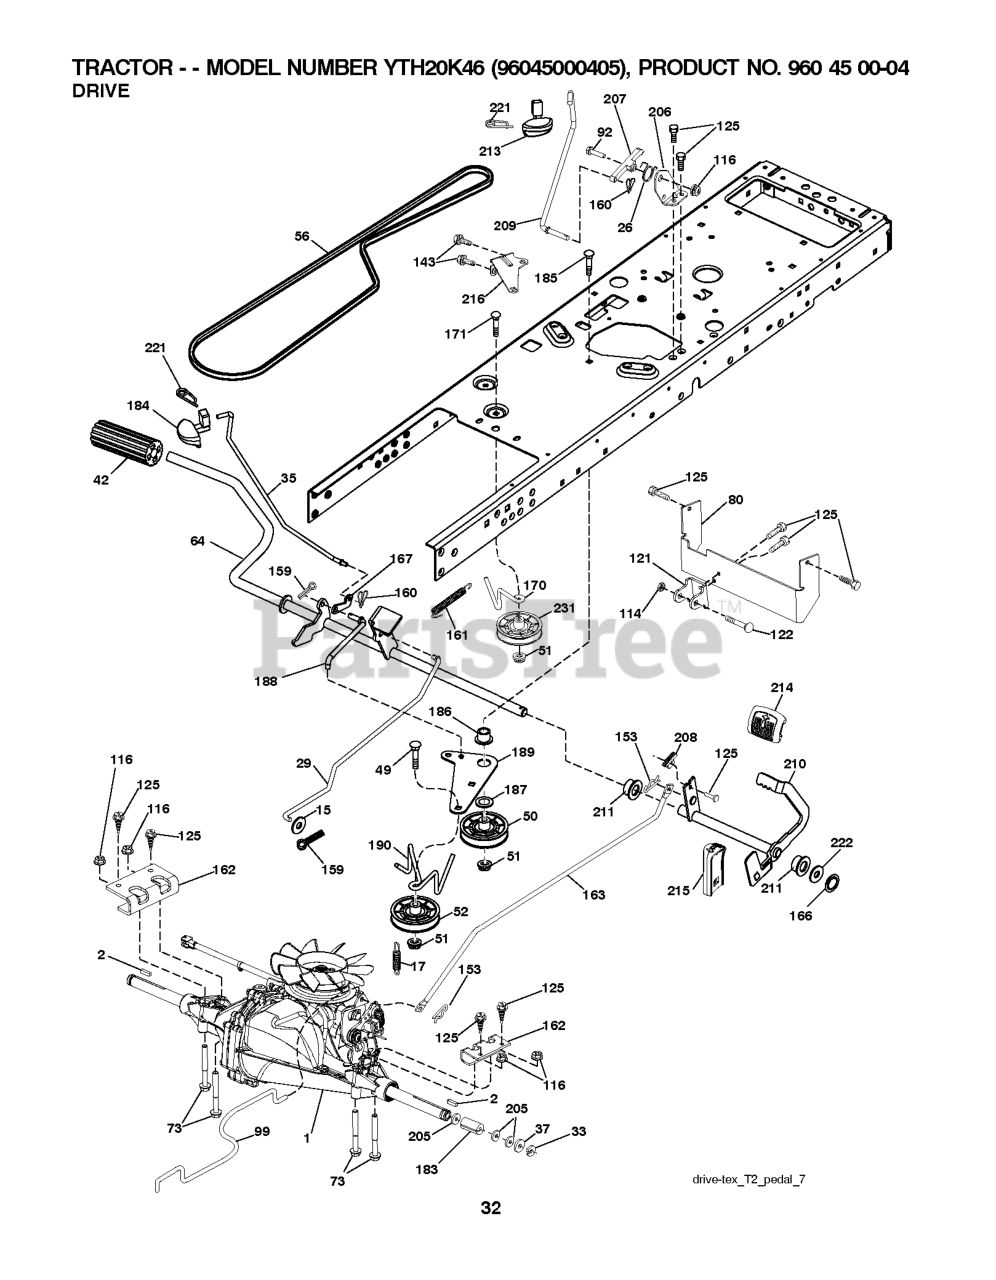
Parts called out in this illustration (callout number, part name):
2	SQUARE KEY
15	WASHER
17	SPRING.BRAKE.HG3000/3500
26	SPRING.RETURN.CRUISE
29	ROD.BRAKE.T2.TEX
35	ROD.BRAKE.PARKING.GT.H
42	PEDAL COVER T
50	IDLER.FLAT.910.OFFSET
51	NUT LOCK FLG 3/8-16 UNC
52	IDLER.V-GROOVE.910.OFFSET
64	SHAFT.ASM.PEDAL.BRK.CNTR
73	BOLT HEX 5/16-18 GR 5
80	RP.STRAP.TORQUE.FS.T2
92	BOLT
99	ROD.ASM.BYPASS.SPRING.T2.FS
114	NUT.71038.31-18.HEX.NYLOCK
116	NUT LOCK HEX FLANGE 5/16-18
121	BRACKET STRAP TORQUE
122	BOLT.5/16-18X2.5
125	SCREW
143	Screw 5/16-18 x 1/2 Hex, Self Tapping 5/16-18 x 1/2
153	RETAINER M
159	COTTER PIN
160	RETAINER CLIP
161	SPRING, RETURN LT
162	ADAPTER.TRANSAXLE.T2.TLT.DRWBR
163	ROD.CONTROL.PCH.T2.TEX
166	NUT.PUSH.625.2006
167	LATCH.BRAKE.SPRING
170	KEEPER.CENTER SPAN.1.688
183	SPACER, AXLE PVST
184	HANDLE.PARKG.BRK.HUSQ X667
186	SPACER.RETAINER
187	WASHER 12/32X2X10GA
188	RP.LINK.CLUTCH.GROUND.DRIVE
189	BELLCRANK.GROUND.DRIVE.TEX.
190	KEEPER.BELLCRANK.DRIVE
206	BRKT.MOUNT.LATCH.CRUIS
207	LATCH.CONTROL.CRUISE
208	GEAR.SECTOR.CONTROL.CR
209	ROD.CONTROL.CRUISE.GT.
210	ROCKER.ASM.PEDAL.CONTR
211	BEARING.NYLON
213	KNOB.CONTROL.CRUSIE.HU
214	PEDAL.FORWARD.TEX.GT.4
215	PEDAL.REVERSE.TEX.GT.4
216	BRACKET.PULLEY.IDLER.W/TEX
221	RETAINER.SPRING.CLIP.H
222	WASHER 21/32 X 1-1/4 X 10 GA.
231	IDLER.V-GROOVE.1.688.OFFSET
